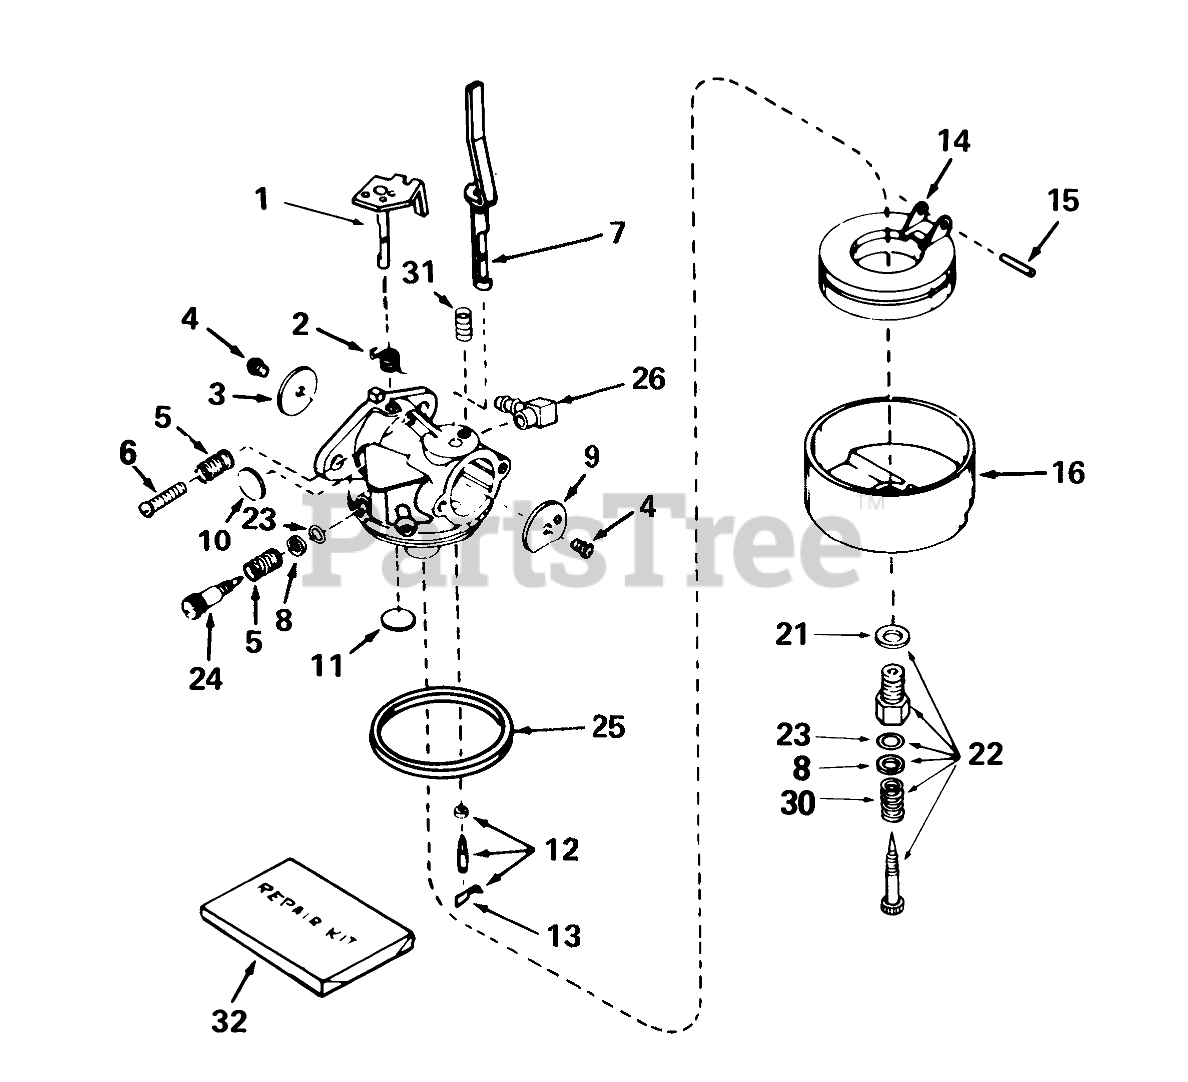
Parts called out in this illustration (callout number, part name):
1	Throttle Shaft and Lever ASM
2	Spring, Return
3	Shutter-Throttle
4	Screw-Shutter
5	Spring-Tension
6	Screw-Throttle Crack Screw / Idle Speed
7	Shaft & Lever Assy., Choke
9	Shutter-Choke
10	Plug-Welch, Idle Mixture Well
11	Plug-Welch, Atmospheric Vent
12	Inlet Needle, Seat & Clip Assy. (Incl. #13)
13	Clip-Spring
14	Float
15	Shaft-Float
16	Bowl-Float (no drain)
21	Washer-Bowl Nut
22	Adj. Screw Assy., Main (Incl. #8, 21, 23 & 30)
23	"O"Ring
24	Screw, Idle Adj.
25	O Ring-Bowl, Float
26	Fitting-Fuel
31	Spring-Positioning, Choke
32	Repair Kit (Incl. items marked )
